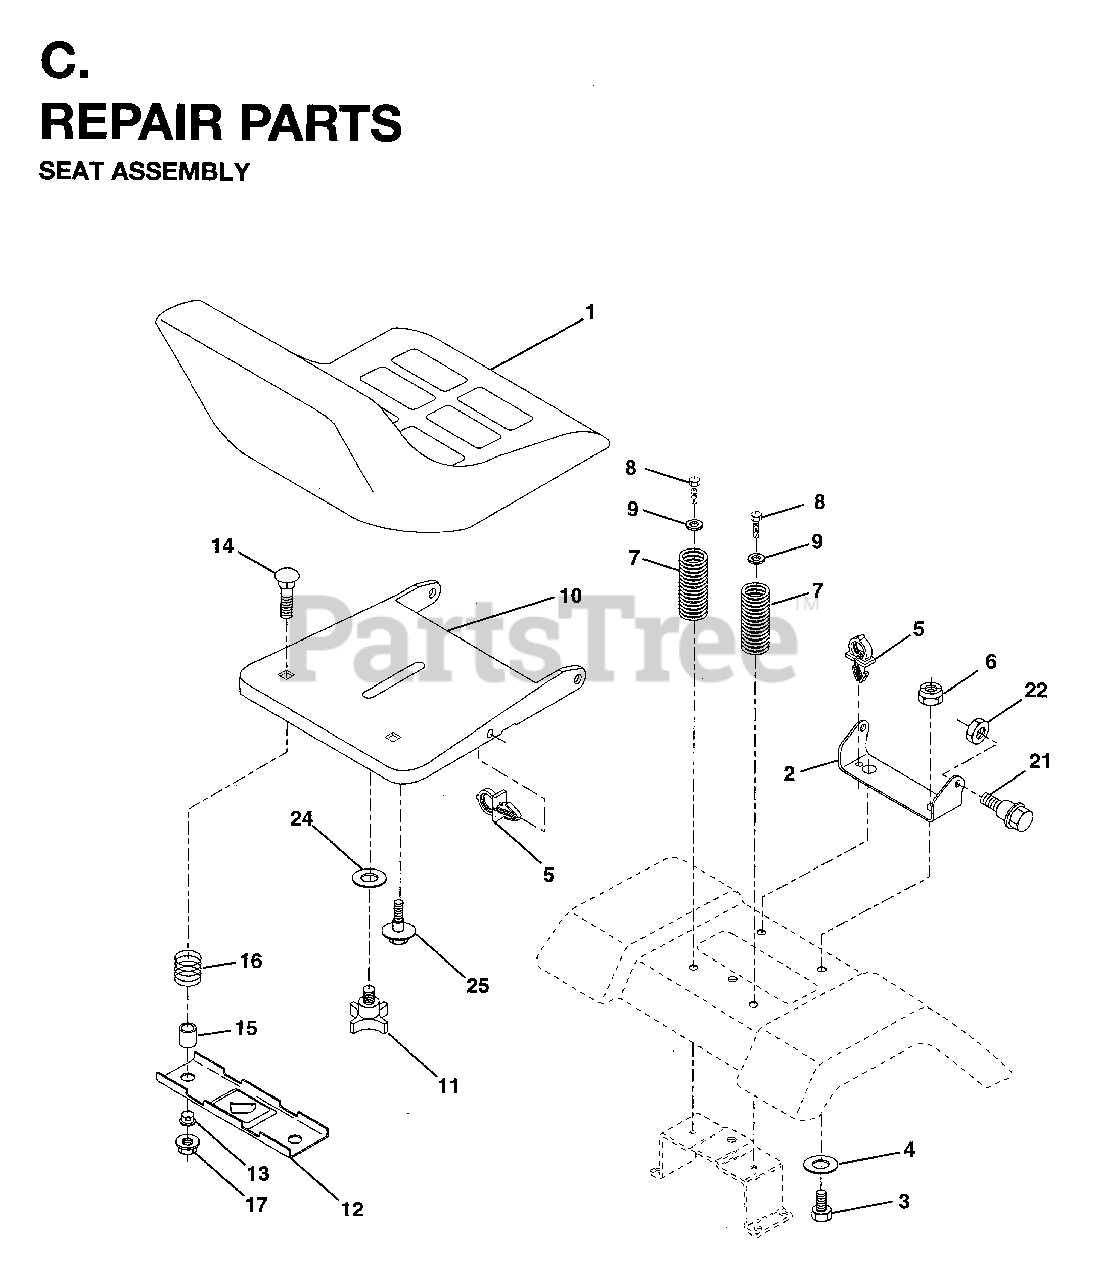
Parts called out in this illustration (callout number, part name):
1	SEAT
2	SEAT PIVOT BRKT
4	WASHER PM
5	PUSH CLIP
6	LOCKNUT
7	SPRING COMPRESSION
9	WASHER
10	SEAT PAN
11	KNOB 1/2" YT
12	BRKT SWITCH
14	BOLT CARRIAGE 1/4-20X1 3/8
15	SPACER SPLIT
16	SPRING COMPRESSED
17	NUT.CROWNLOCK.1/4
22	LOCKNUT
25	BOLT,SHOULD
